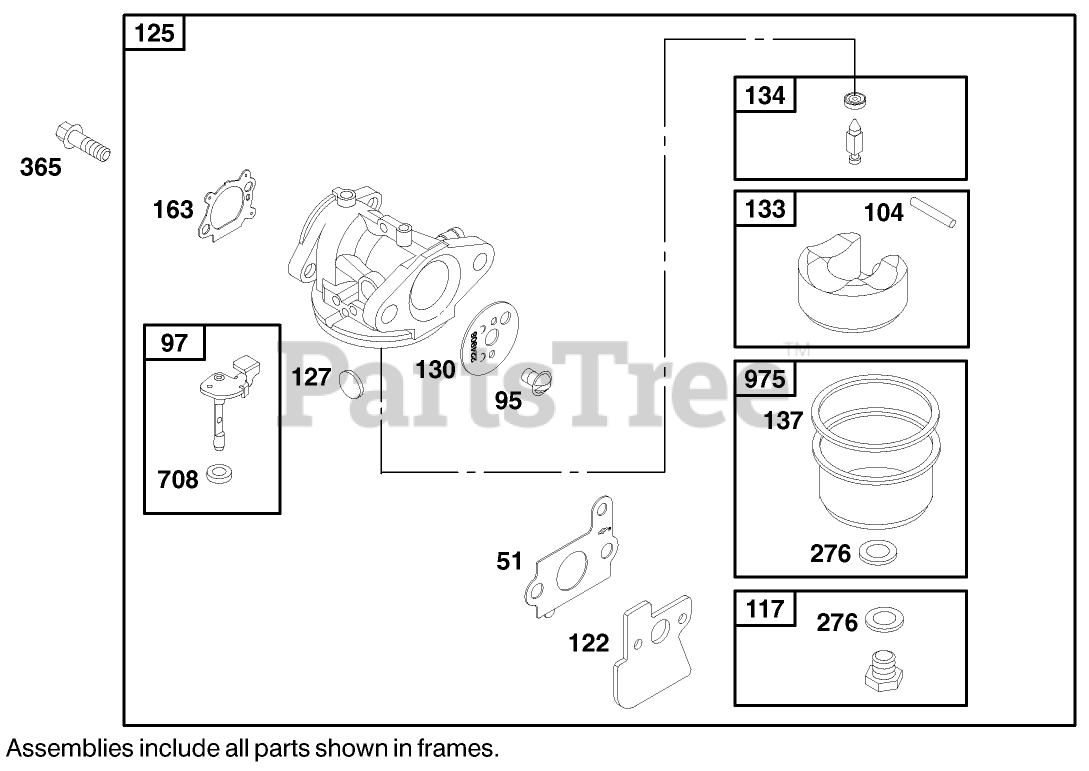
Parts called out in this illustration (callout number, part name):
51	Gasket-Intake
95	Valve-Choke
97	Shaft?Throttle
104	Pin-Hinge, Float
117	Jet-Main
122	Gasket-Intake
125	Carburetor
127	Welch Plug (Sold in Kit Only)
130	Valve?Throttle
133	Float-Carburetor
134	Valve-Inlet (Includes Seat)
137	Float Bowl Gasket (Sold in Kit Only)
163	Air Cleaner Gasket
276	Bowl Washer (Sold in Kit Only)
365	Screw
708	Seal-Shaft, Choke Throttle
975	Bowl-Float
